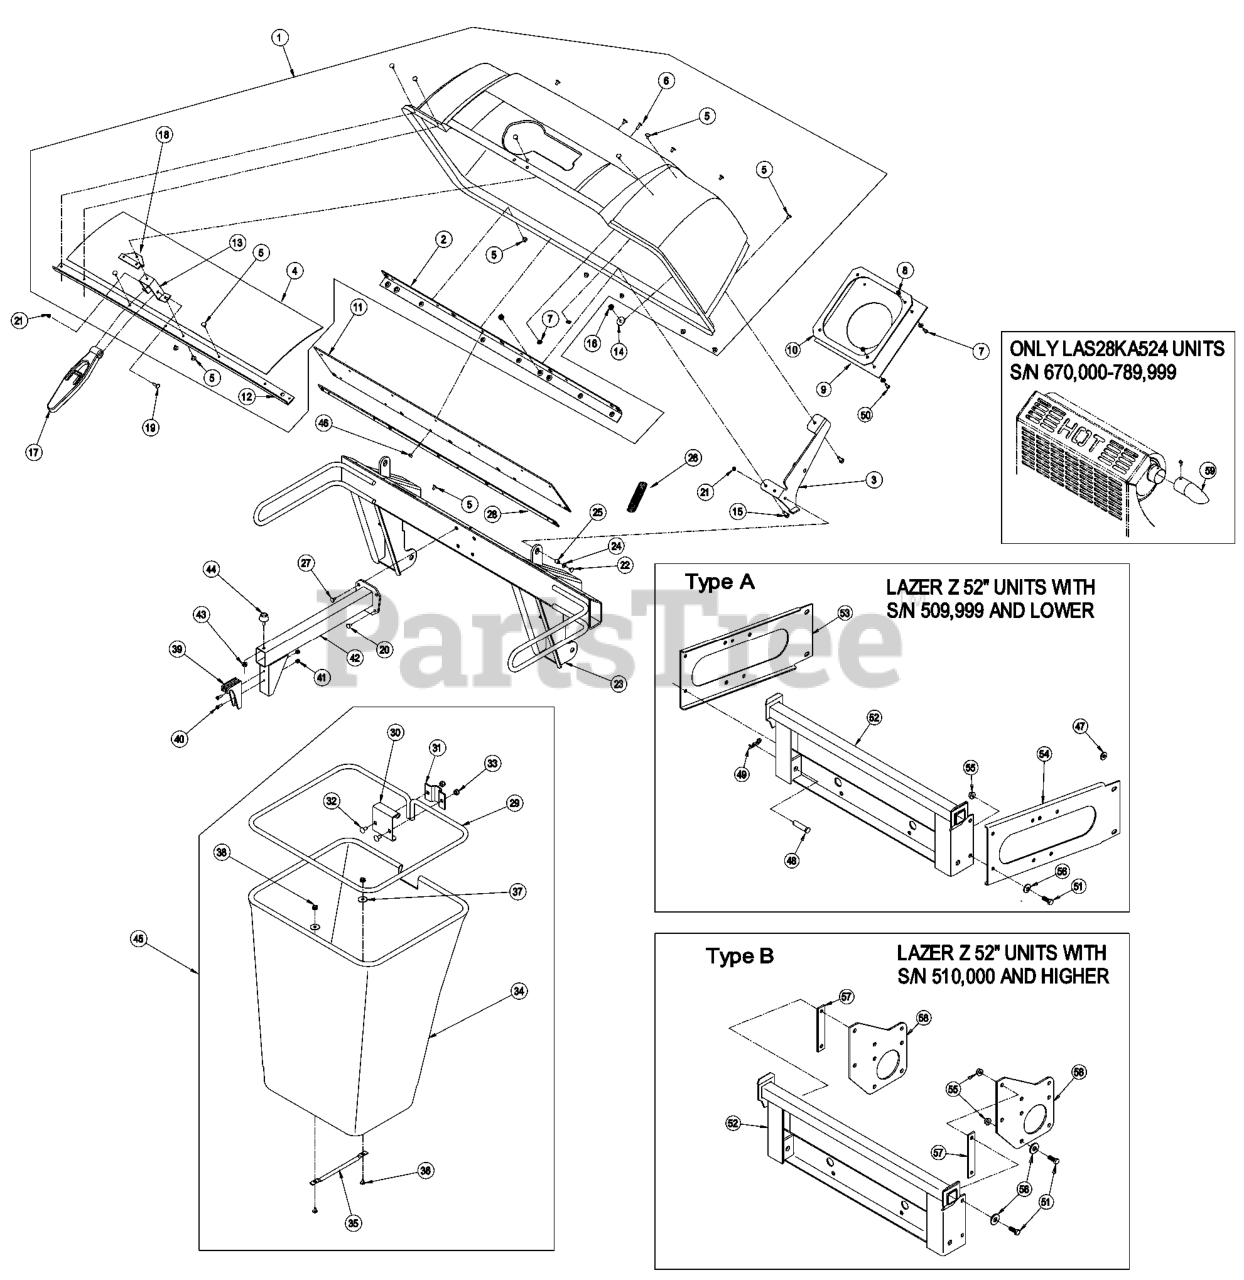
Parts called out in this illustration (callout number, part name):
1	ASM, HOOD
2	STIFFENER-BAGGER, TOP
3	HINGE-RH
4	SCREEN-BAGGER
5	RIVET-BLIND
6	SCREW-HEAD, TRUSS
7	WASHER-FLAT
8	NUT-LOCK, NI
9	SEAL-CHUTE
10	CLAMP-SEAL
11	SEAL-HOOD
12	SUPPORT-SCREEN
13	ANCHOR-LATCH
15	SCREW-HH
18	REINFORCEMENT-LATCH
19	SCREW-HH
20	SCREW-HSBH
21	NUT-LOCK, NI
22	SCREW-HH
23	UPRIGHT-BAGGER
24	WASHER-FLAT
26	SPRING-EXTENSION
27	SCREW-HH
28	PLATE-BACKING
29	FRAME-BAG
30	HANGER-BAG
32	BOLT-CARR
33	NUT-LOCK, NI
35	HANDLE-BAG
36	BOLT-CARR
38	NUT-LOCK, NI
40	SCREW-PPH
42	SUPPORT-BAG
45	BAG AND FRAME ASM
46	NUT-LOCK, SIDE
47	SPACER
48	PIN-CLEVIS
49	PIN-COTTER
50	SCREW-PPH
51	SCREW-HH
52	MOUNT-BAGGER
53	BRACKET-FRAME, LH
54	BRACKET-FRAME, RH
55	NUT-HHF, WHIZ
56	WASHER-BELLEVILLE
57	PLATE-MOUNT, BAGGER
58	TUBE,EXHAUST DEFLECTOR
59	PLATE,REINFORCEMENT LARGE
